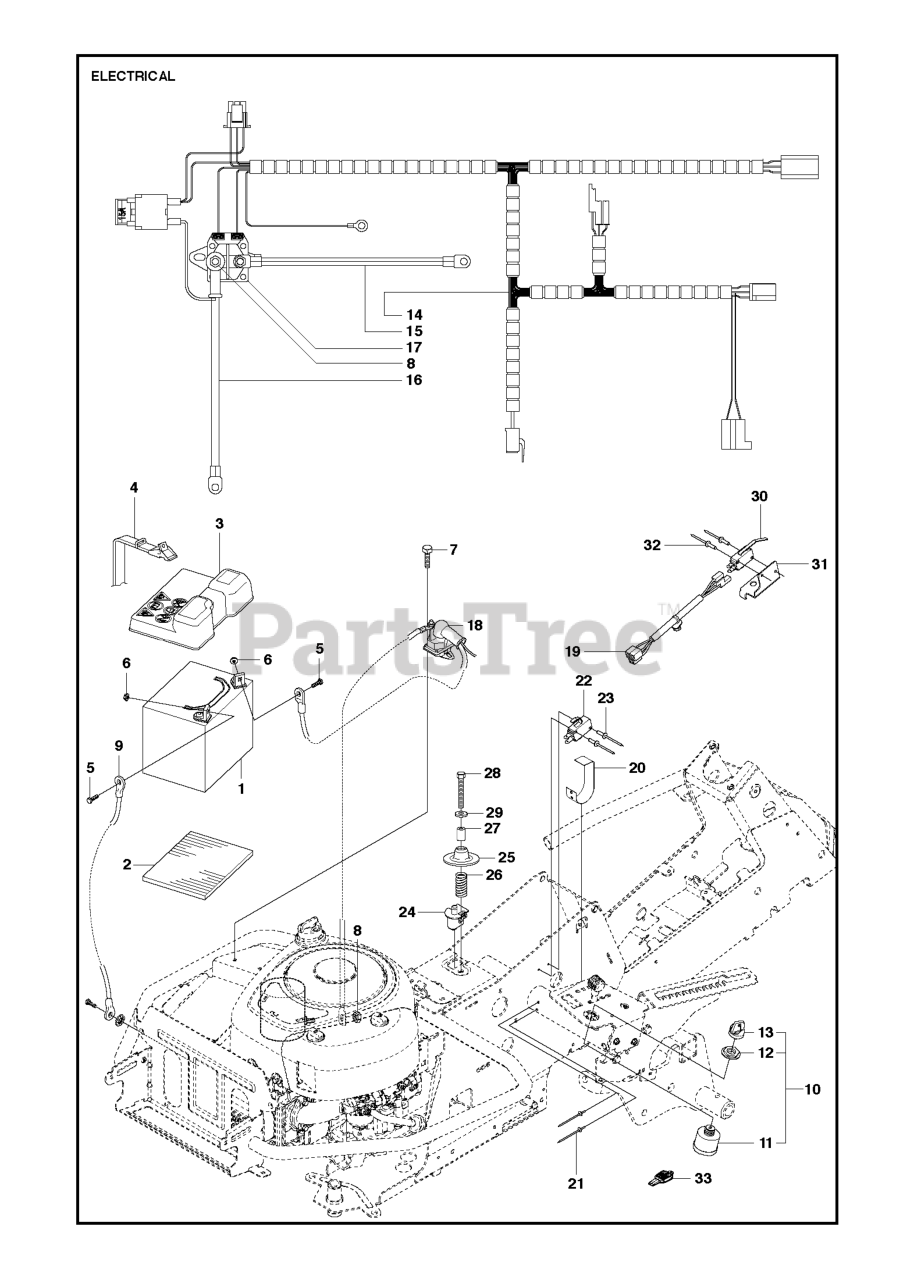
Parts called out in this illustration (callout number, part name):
3	COVER
5	SCREW EHHM
10	IGNITION SWITCH
11	IGNITION SWITCH
13	IGNITION KEY
15	CABLE
18	NUT
19	WIRING
27	SPACER TUBE
28	SCREW
29	WASHER BRB 8.4X17
30	MICRO SWITCH
